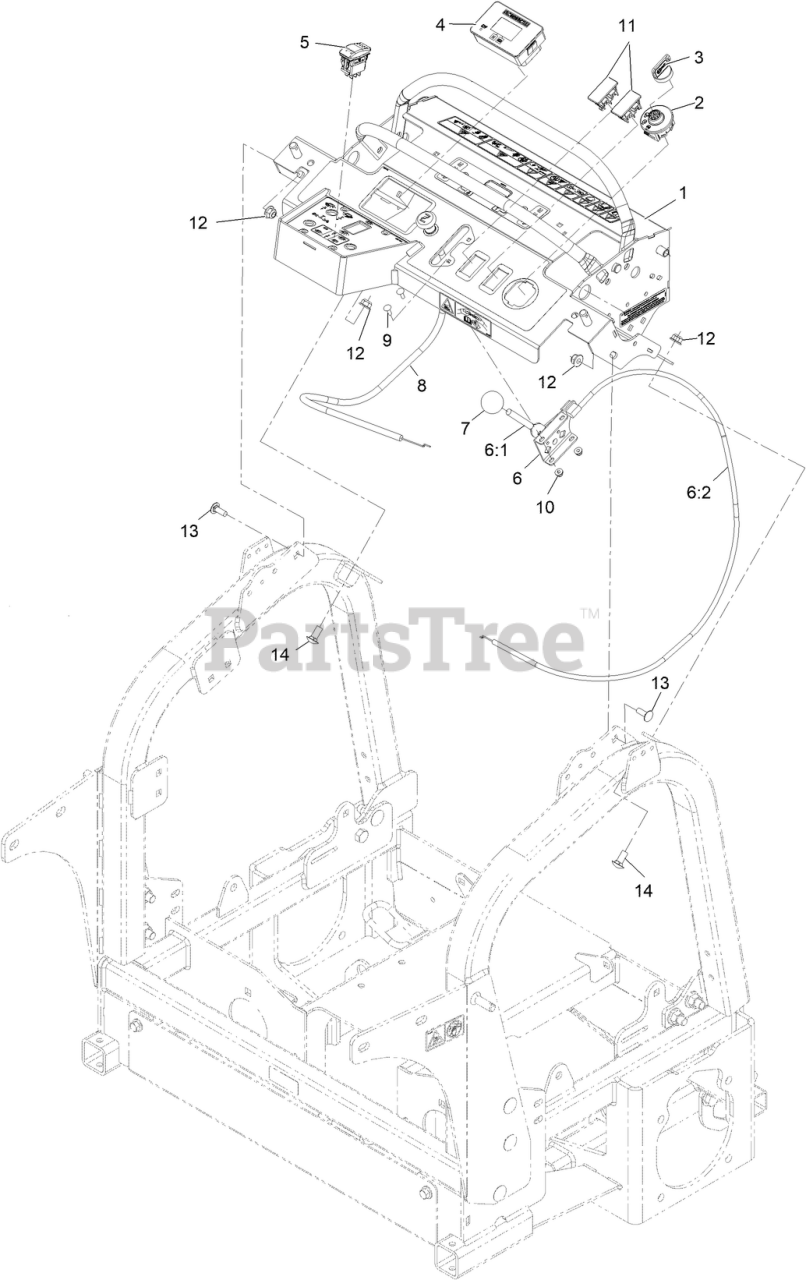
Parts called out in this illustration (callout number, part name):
1	CONTROL PANEL ASM W/DECALS
2	SWITCH-IGNITION
3	KEY-IGNITION
4	HOUR METER ASM
6	CONTROL-THROTTLE ASM
6:1	LEVER-THROTTLE
6:2	Cable-Throttle
8	CABLE-CHOKE
9	BOLT-CARR
11	PLUG-HOLE
12	NUT-HF, NI
13	BOLT-CARR
14	SCREW-CARR
